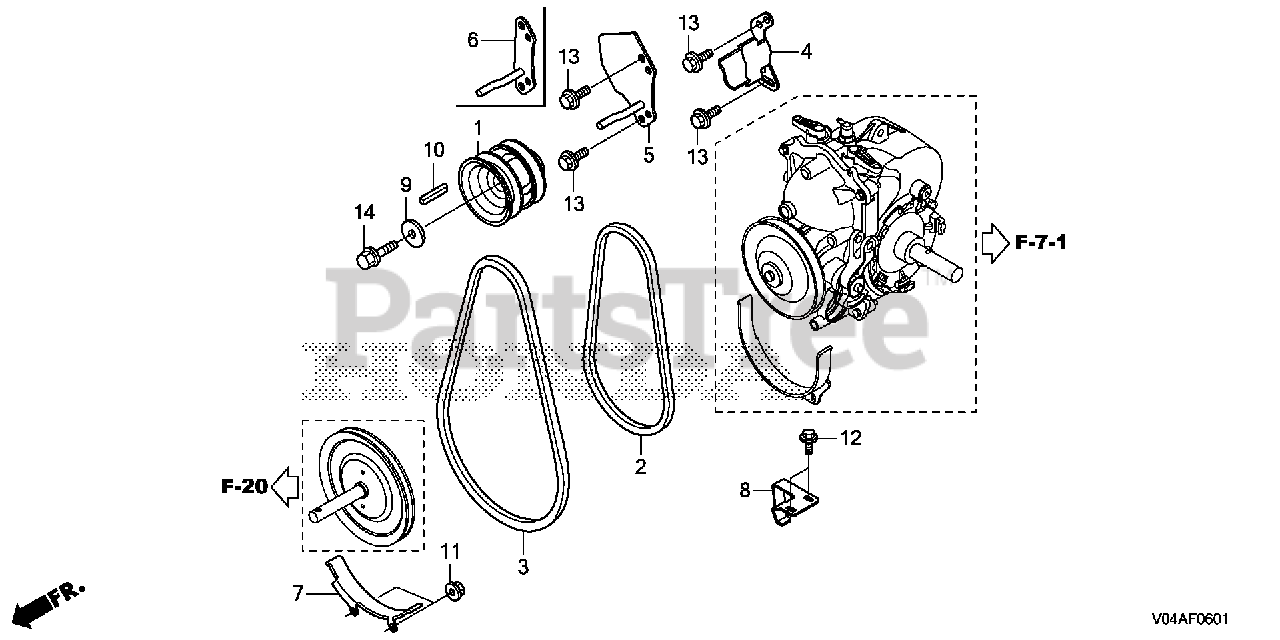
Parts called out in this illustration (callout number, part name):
1	PULLEY, DRIVE
2	V-BELT (SA-37) (W400)
3	V-BELT (SB-41.5) (W800)
4	STOPPER, L. BELT
6	STOPPER, R. BELT
7	STOPPER, AUGER BELT
8	GUIDE, BELT
9	WASHER, LOCK (8MM)
10	KEY (5MM)
11	NUT, FLANGE (6MM)
12	BOLT, FLANGE (6X14)
13	BOLT, FLANGE (8X16) Use from Engine SN 1000016.
14	BOLT, FLANGE (8X28)
